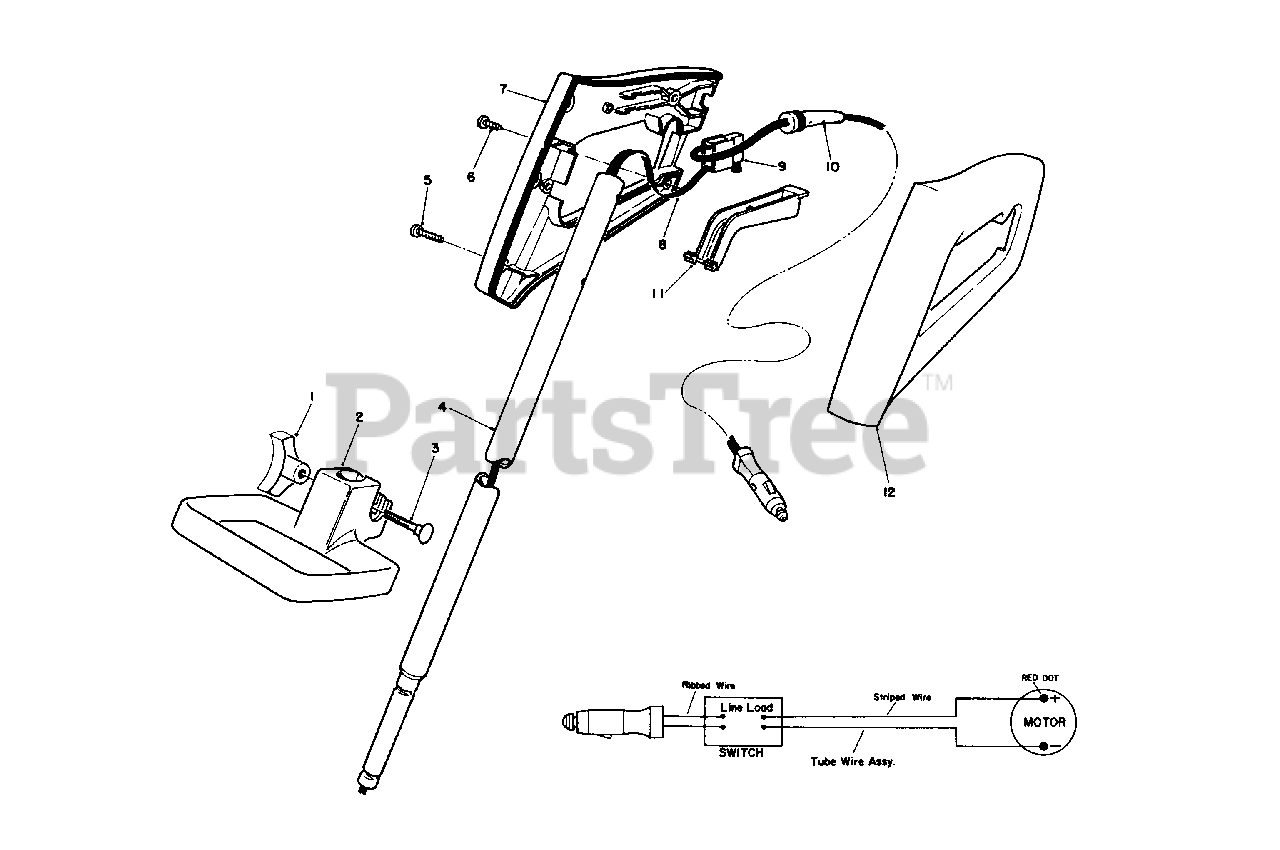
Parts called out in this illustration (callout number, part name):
1	Knob-Adjust
2	Handle-Adjust
3	Bolt-Carriage
4	Tube-Handle
5	Screw-Thread Forming
6	Screw-Thread Forming
7	Grip-Handle, R.H.
8	Wire Assembly-Tube
10	Cord Assembly-Tube
11	Bar-Switch
12	Grip-Handle, L.H.
